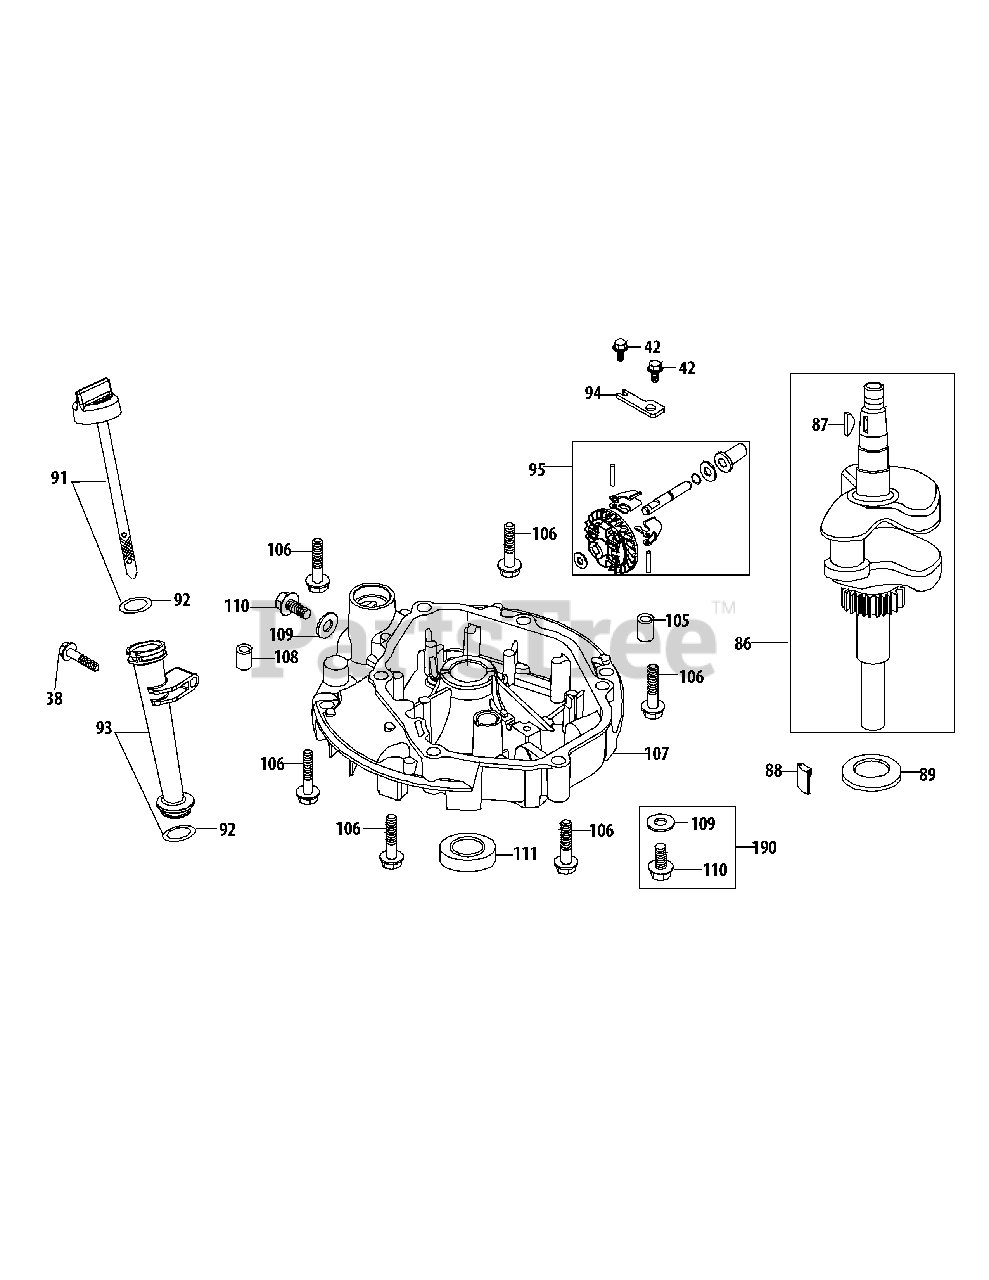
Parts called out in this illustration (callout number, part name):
38	Bolt M6X35
42	Bolt M6X14
86	Crankshaft Assembly
87	Woodruff Key
88	Oil Return Seal
89	Crankshaft Thrust Washer
91	Dipstick Assembly
92	Dipstick / Oil Fill Tube O-Ring
93	Oil Filler Tube Assemlby
94	Governor Gear Mounting Plate
95	Governor Gear/Shaft Assembly
105	Crankcase Cover Dowel Pin 7×14
106	Bolt M6X28
107	Crankcase Cover
108	Crankcase Cover Dowel Pin 9×14
109	Oil Drain Plug Washer
110	Oil Drain Plug
111	Lower Crankshaft Seal
190	Oil Drain Plug and Washer Ass'y
